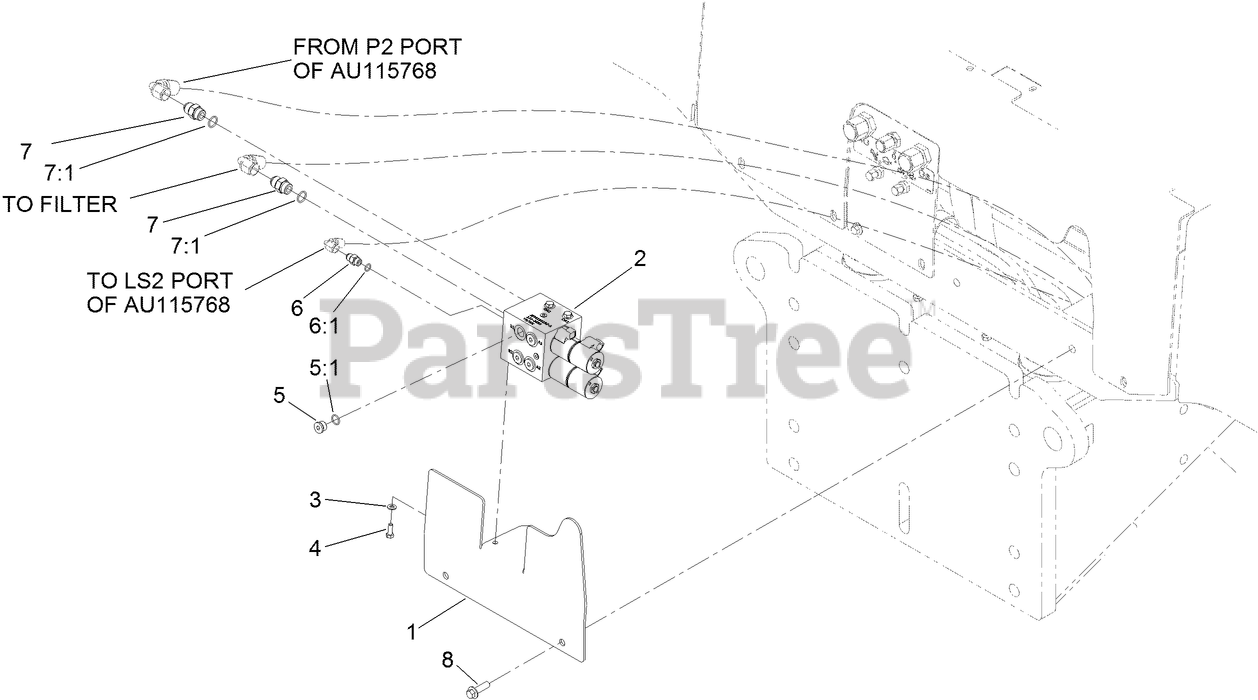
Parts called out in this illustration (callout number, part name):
1	PLATE-MOUNT, VALVE
2	VALVE-SOLENOID
3	WASHER-PLAIN
4	SCREW-HH
5	PLUG-HEX
5:1	O-RING
6	FITTING-STRAIGHT
6:1	O-RING
7	FITTING-STRAIGHT
7:1	O-RING
8	SCREW-HHF
